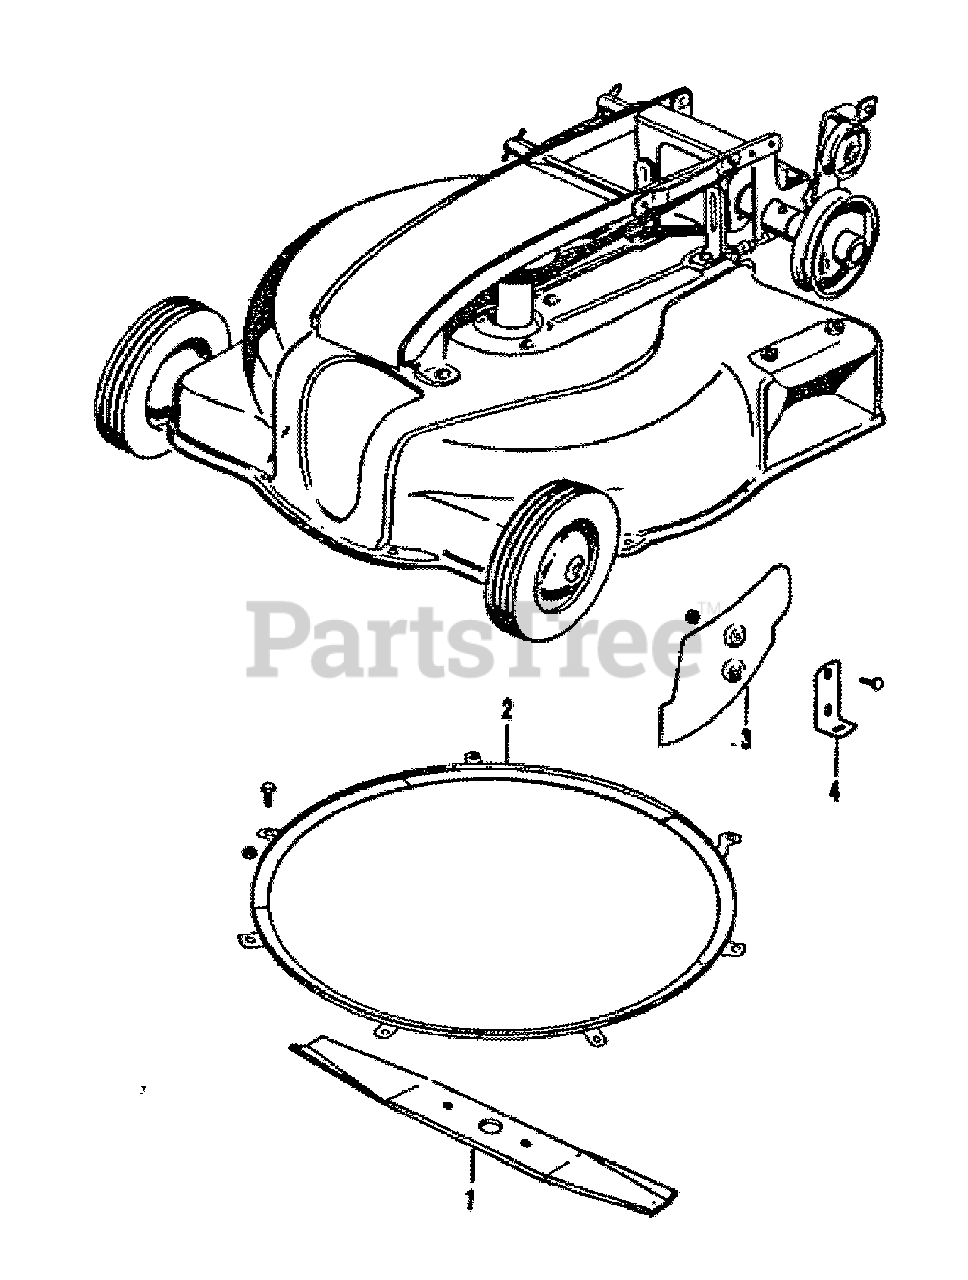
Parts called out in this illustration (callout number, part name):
1	KNIFE BLADE, 20" Only
2	RING ASSEMBLY, 20" Only
3	PLATE, Baffle, 20" Only
